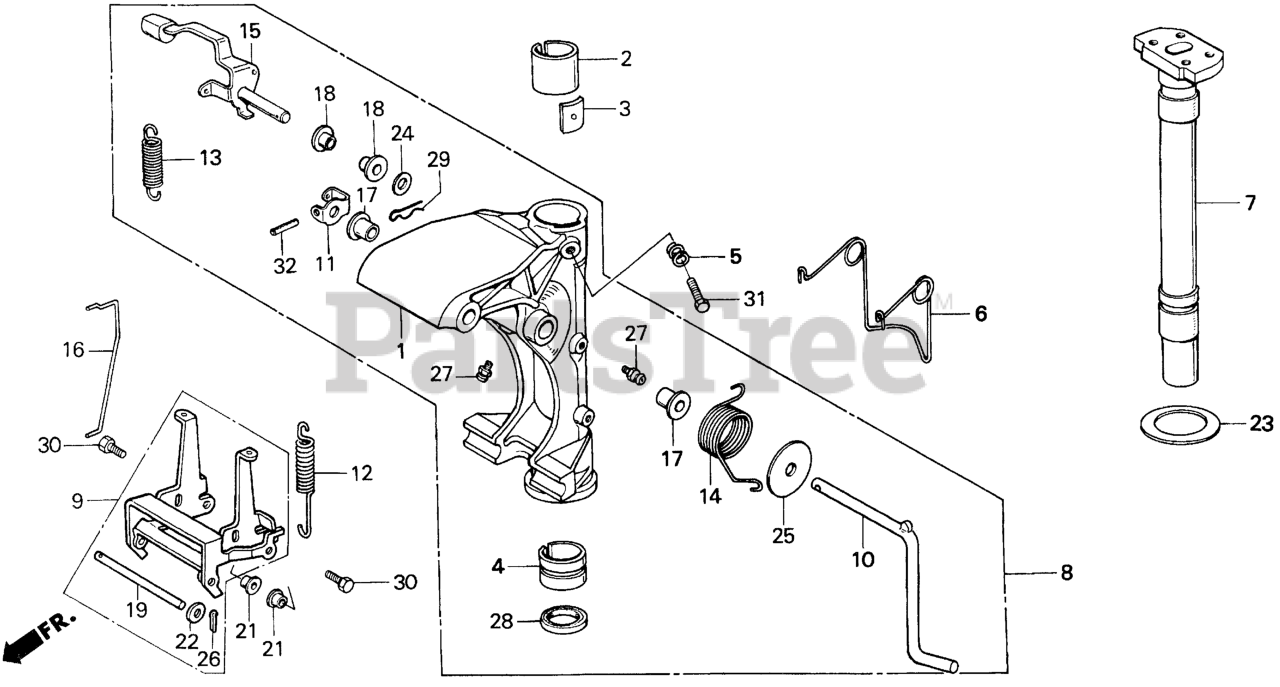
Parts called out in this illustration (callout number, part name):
1	CASE, SWIVEL *B9* (ATLANTIS BLUE)
2	LINER, SWIVEL CASE
3	BLOCK, FRICTION
4	BUSH, SWIVEL SHAFT
5	SPRING, FRICTION ADJUSTING
6	SPRING, HOOK RETURN (NOT AVAILABLE)
7	SHAFT, SWIVEL *B9* (ATLANTIS BLUE) (NOT AVAILABLE)
8	CASE, SWIVEL *B9* (ATLANTIS BLUE)
9	LOCK, REVERSE
10	LINK, TILT (NOT AVAILABLE)
11	BRACKET, TILT LEVER (NOT AVAILABLE)
12	SPRING, REVERSE LOCK
13	SPRING, TILT LEVER (NOT AVAILABLE)
14	SPRING, TILT LINK (NOT AVAILABLE)
15	LEVER, TILT (NOT AVAILABLE)
16	ROD, RELEASE SWIVEL CASE (NOT AVAILABLE)
17	BUSH, TILT LEVER (NOT AVAILABLE)
18	BUSH B, TILT LEVER (NOT AVAILABLE)
21	COLLAR (6MM)
23	WASHER, THRUST
24	WASHER, PLAIN (10MM)
25	WASHER, PLAIN (10MM) (NOT AVAILABLE)
27	FITTING, GREASE
28	OIL SEAL (32X37X7)
29	PIN, LOCK (10MM)
30	BOLT, HEX. (6X16)
31	BOLT, HEX. (8X20) (NOT AVAILABLE)
32	PIN, SPRING (4X25)
